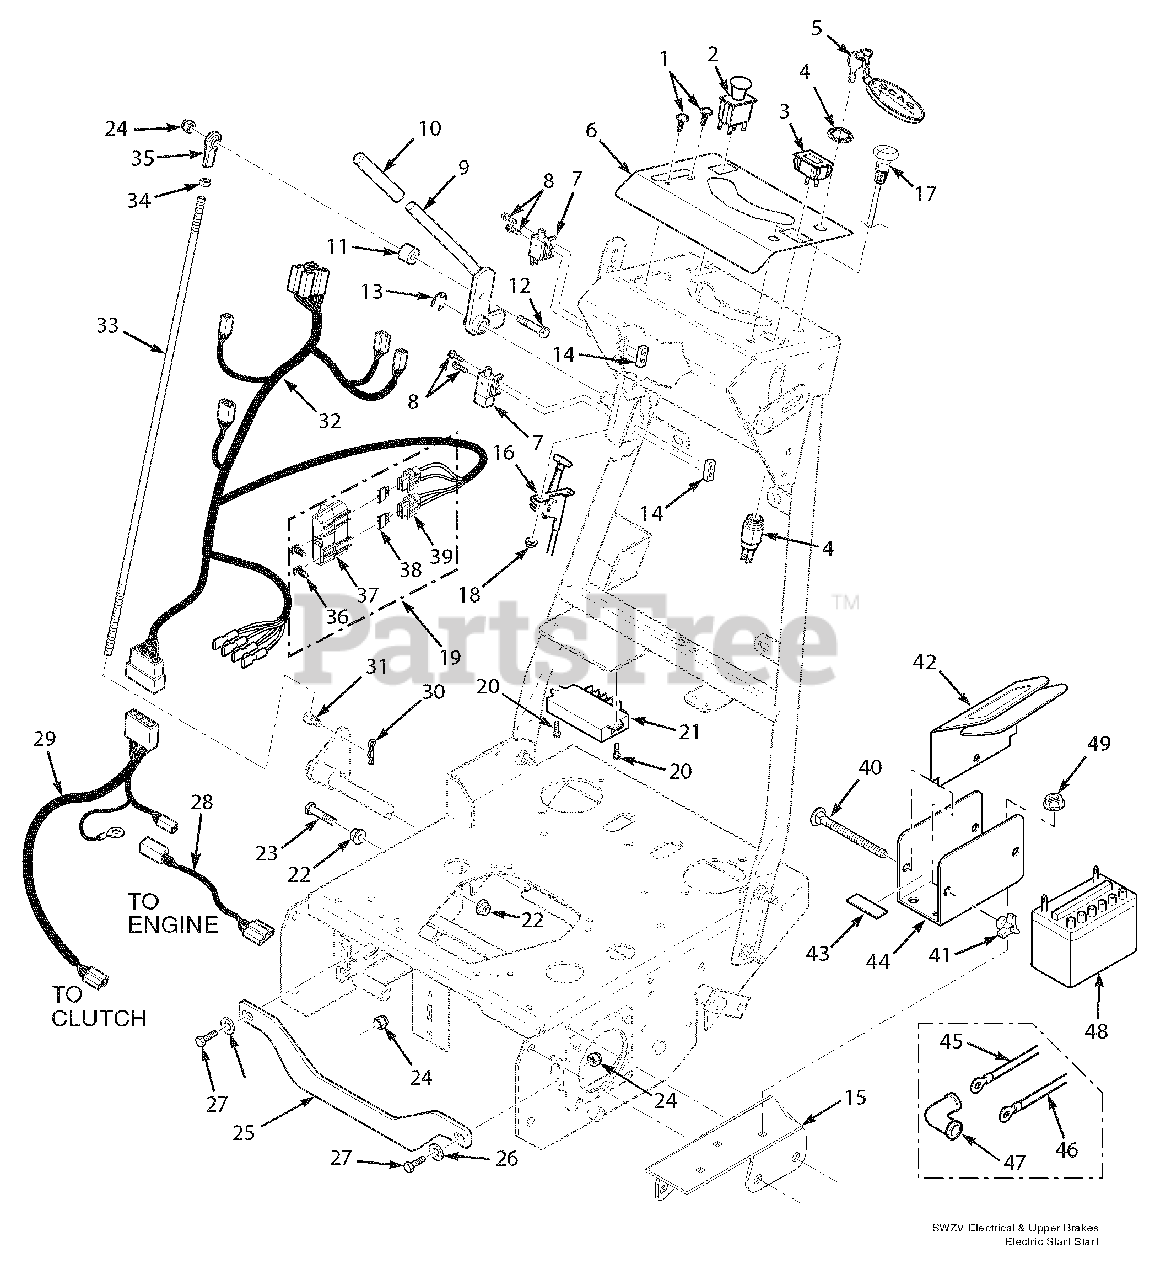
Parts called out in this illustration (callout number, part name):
1	Screw, Phillips #10-32 x 1/2"
2	Switch, PTO
3	Hour Meter
4	Key Switch
5	Key Fob w/Keys
6	Decal, Control Panel
7	Switch, Interlock
8	Screw, Hex Head #10-32 x 3/4"
9	Lever, Brake
10	Grip, Brake
11	Spacer
12	Bolt, Hex Head 3/8-16 x 2"
13	Retaining Ring
14	Plate, Threaded
15	Battery Support Weldment
16	Throttle Control
17	Choke Control
18	Nut, Serrated Flange #10-32
19	Fuse Holder Assembly
20	Screw, Self Tapping
21	M o d ule, Magura Senso Grip
22	N ut, Serrated Flange 3/8-16
23	Bolt, Hex Head 3/8-16 x 2-1/2’
24	Nut, Elastic Stop 3/8-16
25	Stiffener, SWZV
26	Flatwasher, 3/8-.391 x .938 x .105 HD
27	Bolt, Hex Head 3/8-16 x 1-1/4’
29	Wire Harness, Engine Deck Electric Start
30	Hair Pin Cotter, .094 x 1.62"
31	Swivel Joint
32	Wire Harness, Handle Bar Electric Start
33	Rod, Brake Lever
34	Nut, 3/8-24 UNF Jam
35	Rod End, 3/8-24 RH
36	Clip, Wire
37	Cover, Sealed Double
38	Fuse, 20 Amp
39	Fuse Holder
40	Bolt, Carriage 1/4-20 x 6"
41	Wing Nut, 1/4-20 Plastic
42	Battery Box Cover
43	Pad, Rubber
44	Battery Box
45	Cable, Battery - Red
46	Cable, Battery - Black
47	Rubber Boot
48	Battery
49	Nut, Serrated Flange 5/16-18
